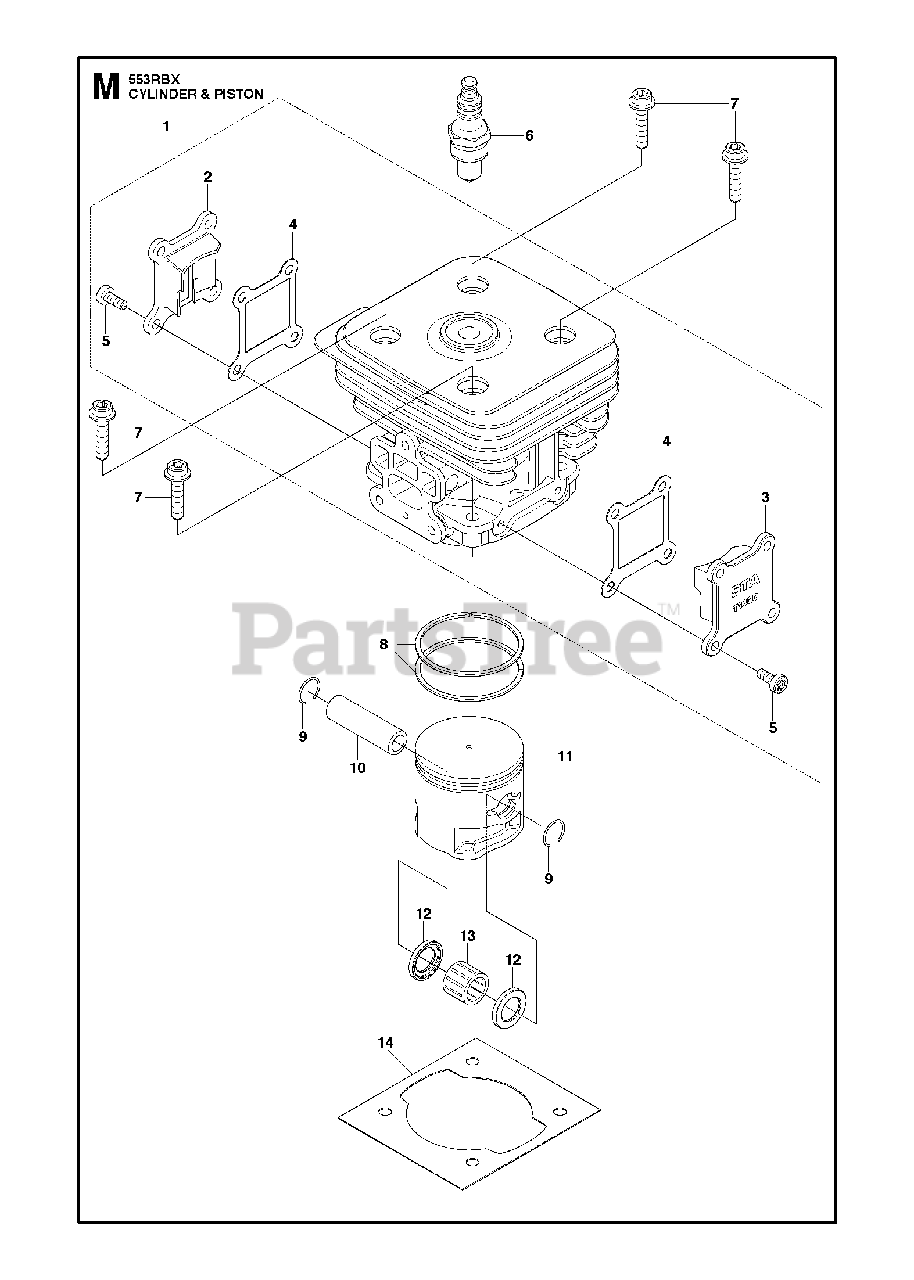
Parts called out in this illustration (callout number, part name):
4	GASKET, TR
5	SCREW
6	PLUG CMR7H
7	BOLT TORX
9	RING, SNAP
10	PIN, PISTON
12	WASHER, THRUST
13	BEARING (RPLS 335041410)
